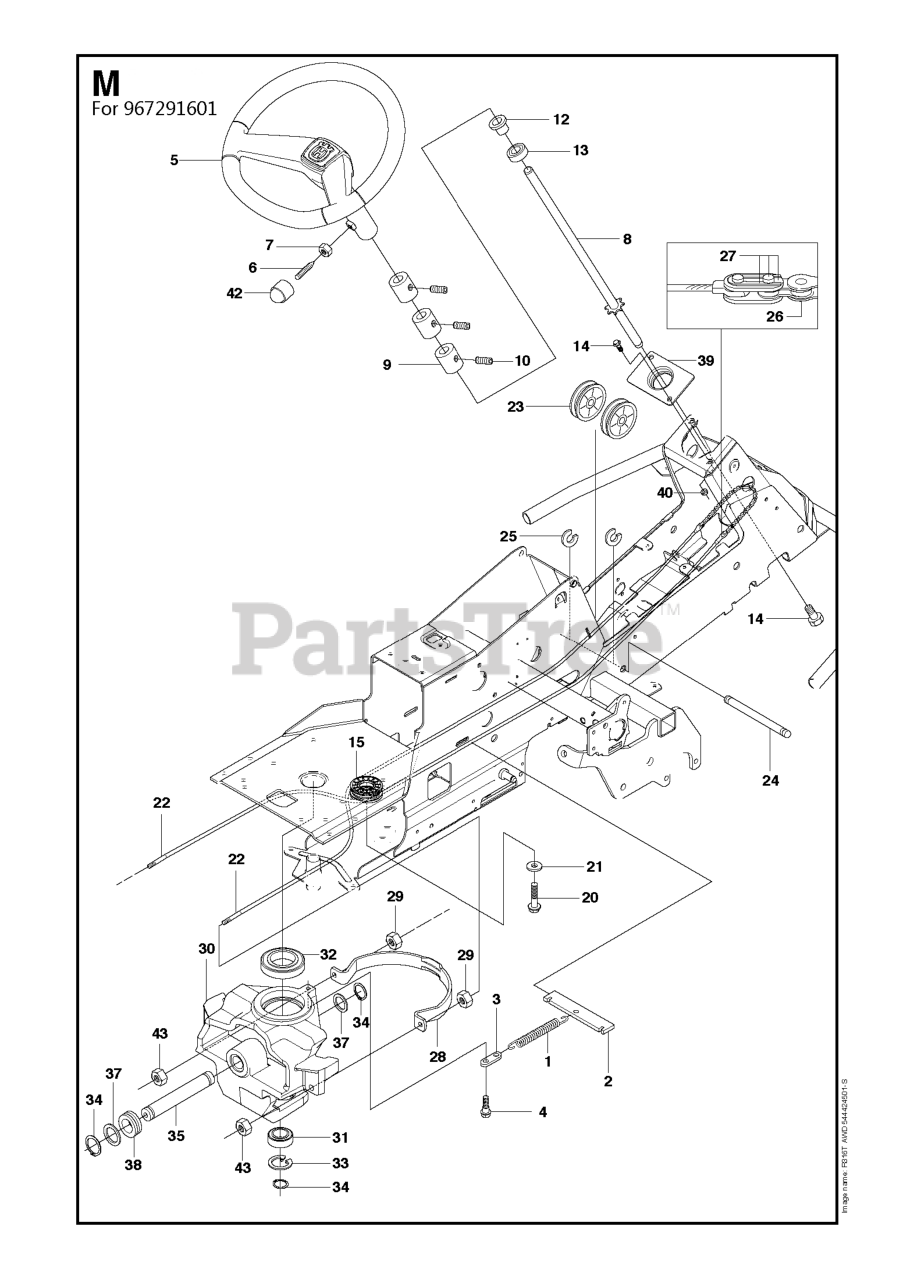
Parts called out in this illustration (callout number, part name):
1	WIRE ASM INNER W/ PLUNGER LT
2	SHAFT ASM R HANDLE
2	SPRING BRACKET
3	PIN GROOVE.
4	RETAINING RING LT
5	STEERING WHEEL
6	BEARING.NYLON
7	GRIP HANDLE
7	NUT
8	PLUNGER BUT KIT
8	STEERING ROD
9	SPACER
11	LINK LIFT LH
12	LINK LIFT RH
13	RETAINER-SPRNG RB
13	BALL BEARING 6004-2RS1
15	LINK.SUSPENSION.FRONT
16	NUT.HEX.JAM.1/2-13
18	NUT.LK.W/WSH.1/2.
19	ARM.REAR.SUSPENSION
20	SPRING RETAINER
20	COLLAR SCREW
22	WIRE ASSY
25	SPRING**
25	RETAINING RING
26	RETAINER CLIP
26	STEERING CHAIN
27	ROD ADJ LIFT
28	NUT
28	WIRE GUIDE
29	KNOB INF 3/8-16
29	NUT
31	BEARING.PIVOT.LIFT
31	Ball Bearing 6005-2rs
32	NUT CROWNLOCK 3/8-24
32	BALL BEARING 6010 2RS1
33	CIRCLIP SGH 47
34	RETAINING RING SGA 25
36	POINTER, HEIGHT INDICATOR(2 2)
38	SCREW 5/16-18X1
40	NUT
41	IND. HEIGHT STLT
42	PROTECTIVE COVER
43	NUT
49	NUT
50	NUT PUSH M
